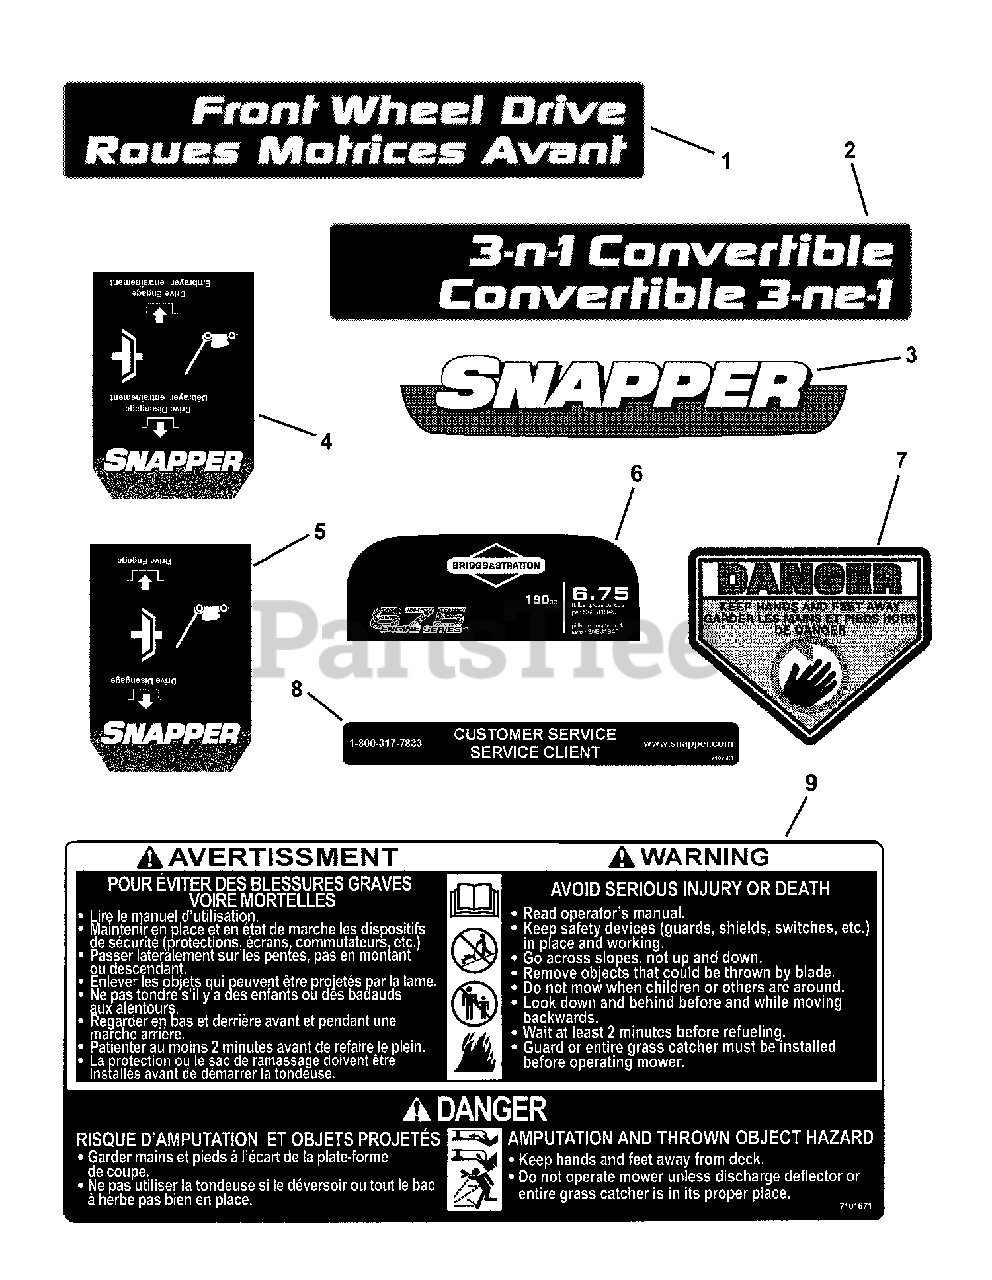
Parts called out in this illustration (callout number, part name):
1	DECAL, Front Cover, 22" Snapper, Front Wheel Drive
2	DECAL, Front Cover, 22" Snapper
3	DECAL, Briggs Engine, Snapper
4	DECAL, Control Head, SS, Snapper, FC
5	DECAL, Control Head, VS, Snapper, FC
7	DECAL, Engine, TP, 650, Snapper, FC (Artwork Not Available)
8	DECAL, CPSC, French/English
9	DECAL, Customer Service, Snapper FC
10	DECAL, French/English, WB Safety
